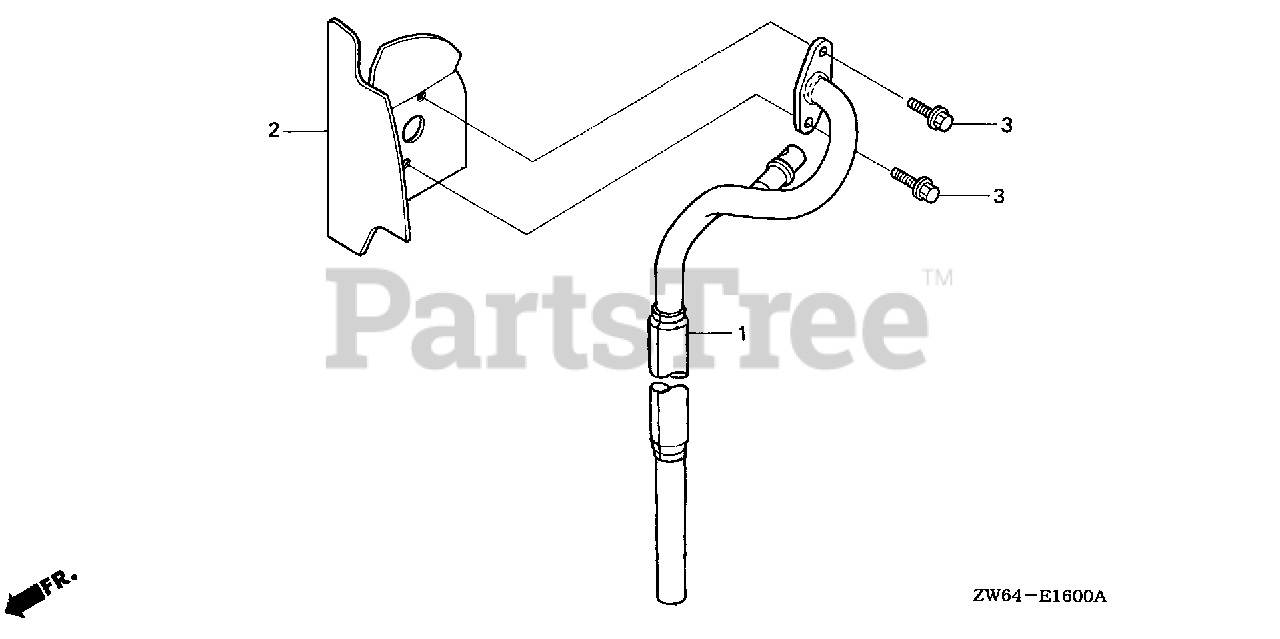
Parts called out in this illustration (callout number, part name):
1	PIPE, EX.
2	GUIDE, AIR EX.
3	BOLT, FLANGE (5X16)
